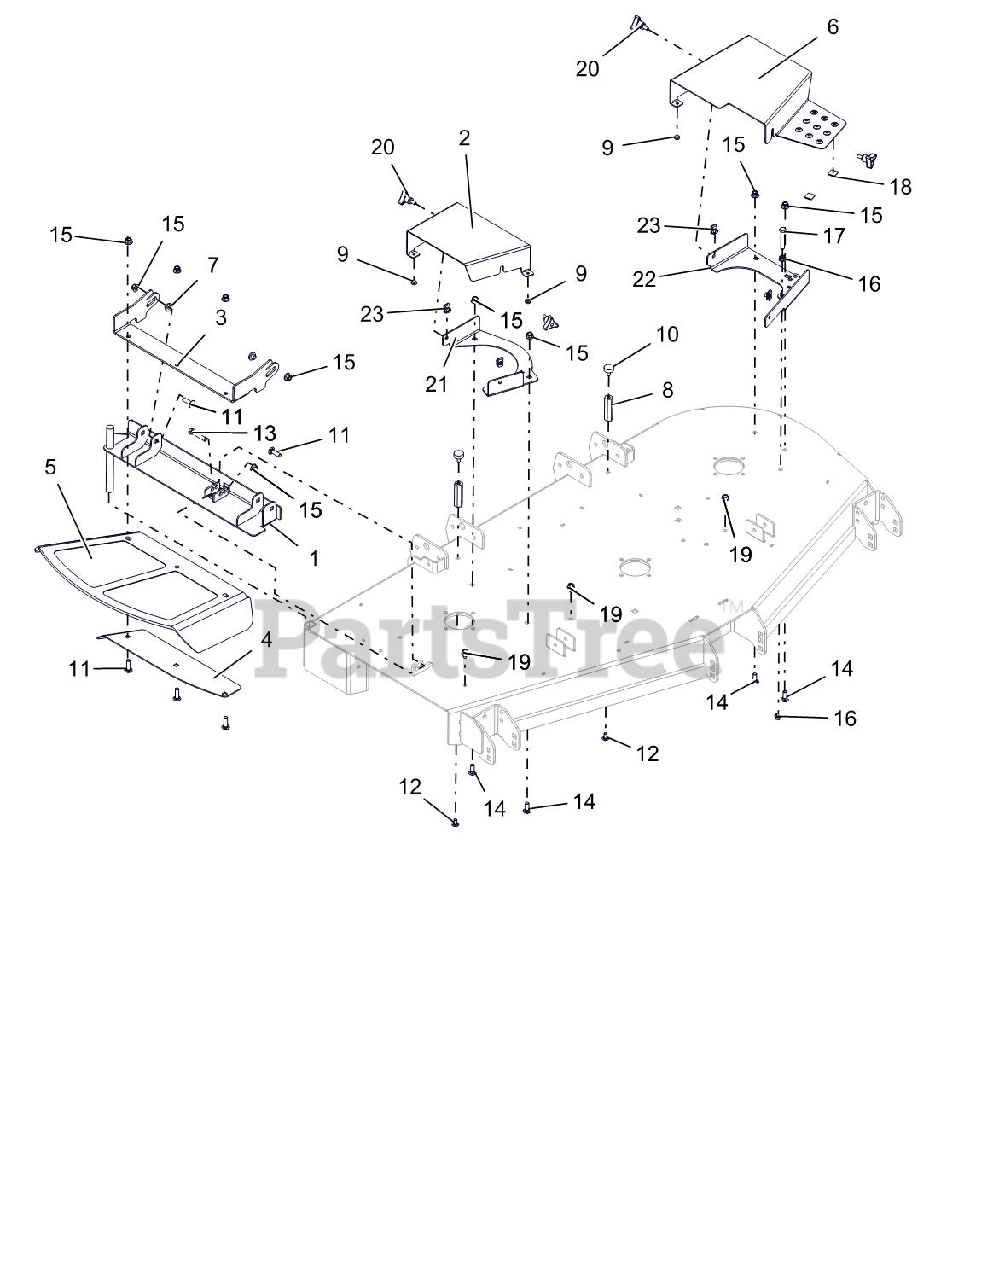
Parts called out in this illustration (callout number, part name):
1	48-60 DISCH CHT MTG WMT W/SAFE
2	PT148-152 DECK RH BELT GRD-RED
3	48-60" CHUTE MTG BRKT - RED
4	48-60 DISCH CHUTE CLMP PLT-RED
5	CHUTE,48-60" FRMD RUBBER DISCH
6	PT100 DECK LH BELT GUARD - RED
7	BSHG-FLG .385X.500X.875X.406
8	NUT, COUPLING .31-18 2.75 LG
9	BUMPER GROMMET
10	BUMPER, RUBBER
11	@BLT-RHDSSQNK .38-16X1.25 G5YZ
12	BLT-RDHDSQSHNK.31-18X.62 YZ-LK
13	@BLT-HEX .38-16X2.00 GR5 YWZC
14	@BLT-RDHDSQNK .38-16X1.00 G5YZ
15	@NUT-LK-NYL-FLG .38-16 YWZC
16	@NUT-SPNLK-FLG .375-16 YWZC
17	@BLT-HEX .38-16X2.25 GR5 YWZC
19	@SCR-TAP .38-16X.50 HWH TR YWZ
20	KNOB,WING STUD 5/16-18 X .75
21	BRKT, RH BELT GUARD MTG - RED
22	BRKT, LH BELT GUARD MTG - RED
23	NUT-CLIP RETAINER 5/16-18X.56
